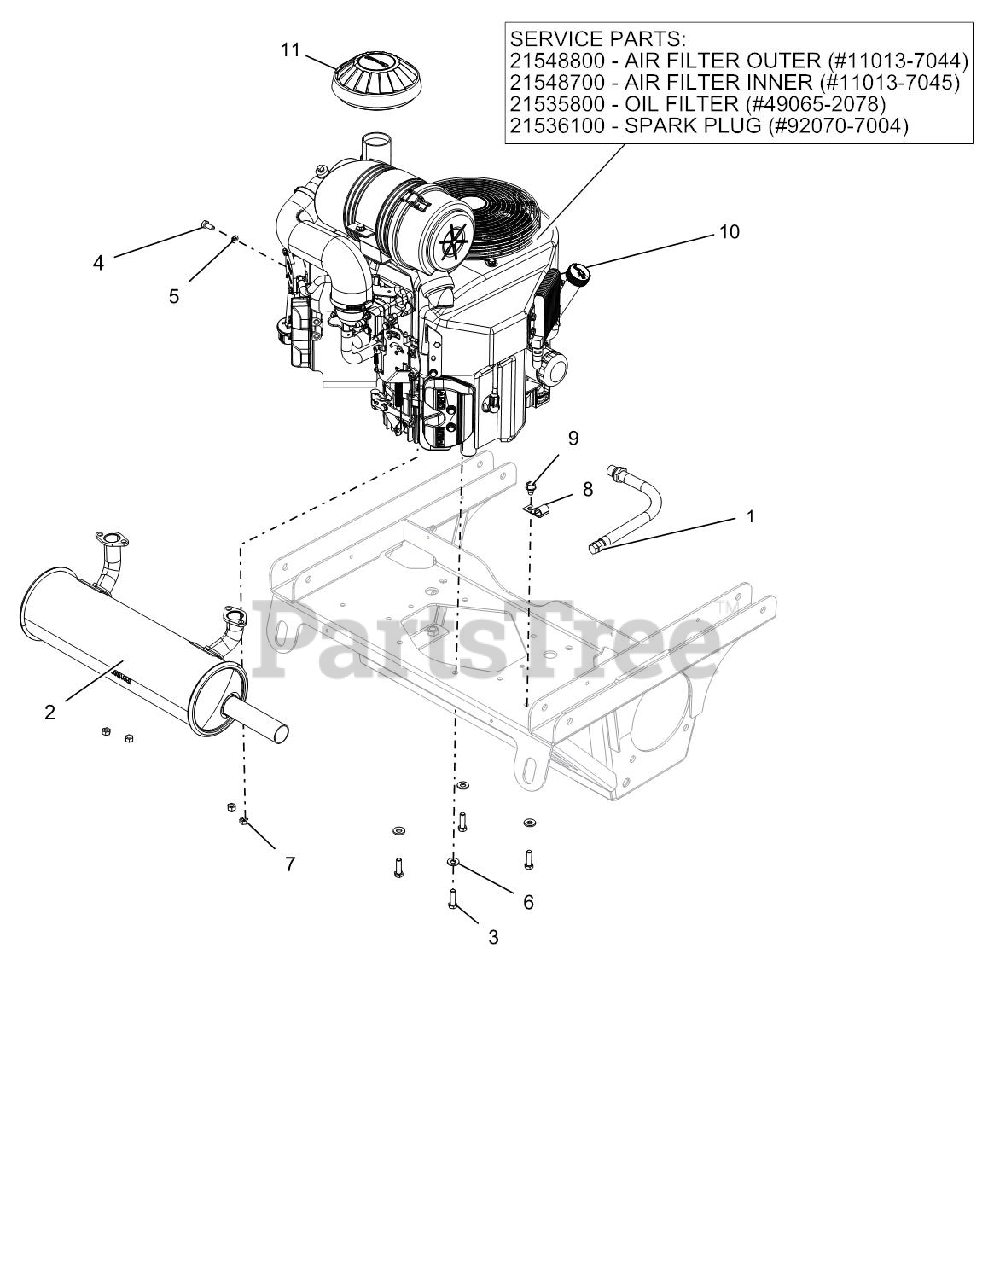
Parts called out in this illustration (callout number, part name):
1	HOSE, OIL DRAIN
2	MUFFLER, 27-31 FX KAW
3	BLT-HEX .38-16X1.25 GR5 YWZC NYTORQ
4	@BLT-HEX M8-1.25X20 YWZC
5	WSHR-LK .31X.078 REG YWZC
6	WSHR, 3/8" SPRING DISC
7	NUT-LK-TOP M8-1.25 YWZC
9	SCR-TAP .38-16X.50 HWH TR YWZ
10	AIR FILTER OUTER, #11013-7044
10	AIR FILTER INNER, #11013-7045
10	OIL FILTER, #49065-2078
10	SPARK PLUG, #92070-7004
10	ENGINE, ENVIROGUARD LP CONVERSION
11	CAP, AIR CLEANER INTAKE (2")
